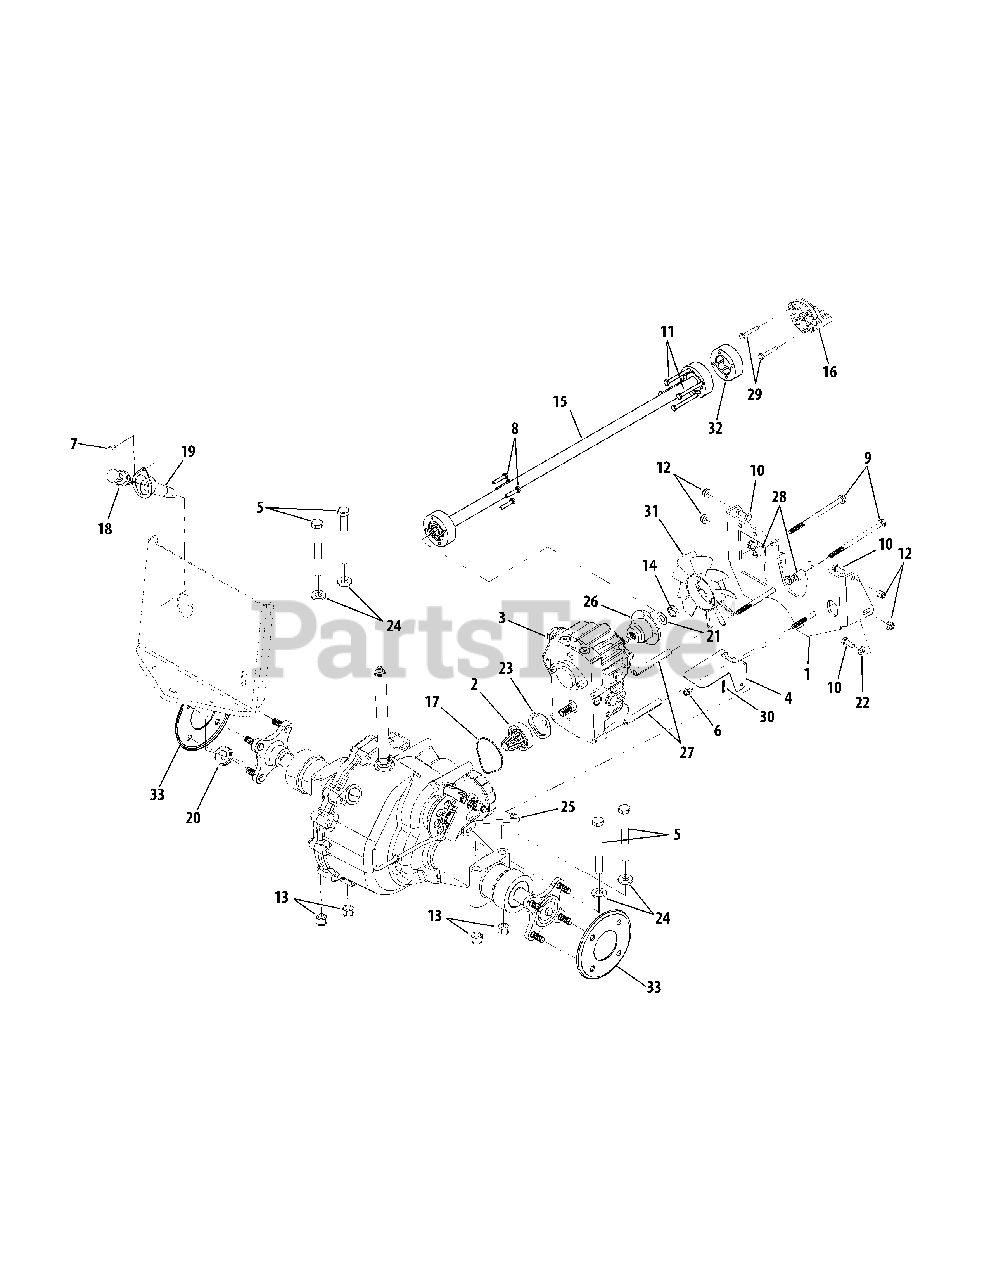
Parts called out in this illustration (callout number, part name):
1	Bracket, Torque
2	Gear Assembly, Pinion
3	Transmission, Hydrostatic
5	Screw, Hex Cap, 1/2-20 x 4.5 GR5
6	Scrw, Hx Wsh Hd Tapp, 1/4-20 x .5
7	Scrw, Hx Wsh Hd Tapp, 10-16 x .44
8	Screw, Hex Patch, 1/4-20 x 1.25 GR5
9	Scrw, Hx Hd Tapp, 5/16-18 x 5.25
10	Screw, Hex Cap, 5/16-18 x .75 GR5
11	Screw, Hex Patch, 1/4-20 x 2.5 Gr5
12	Nut, Hex Lock, 5/16-18
13	Nut, Hex Nylon Lock, 1/2-20 GR2
14	Nut, Hex Top Lock Jam, 1/2-20
15	Shaft, Drive, 29.75 Lg
16	Adapter, Engine
17	Seal, Gland
18	Dipstick, Transmission
19	Holder, Dipstick
20	Grommet, Rubber, .75 x 1.063
21	Washer, Belleville
22	Washer, Flat, .344 x .688 x .065
23	Washer, Spring
24	Washer, Flat, .531 x 1.062 x .134
25	Rod, Hydro Dump Valve
26	Adapter, Hydro Pump
27	Spacer, Hydro, .323 x .443 3.51
28	Spacer, Hydro, .323 x .600 x .74
29	Screw, Hex Patch, M10-1.5x 90mm
30	Internal Cotter Pin
31	Fan, Pump
32	Adapter, Drive Shaft
33	Rim Reinforcement Plate
